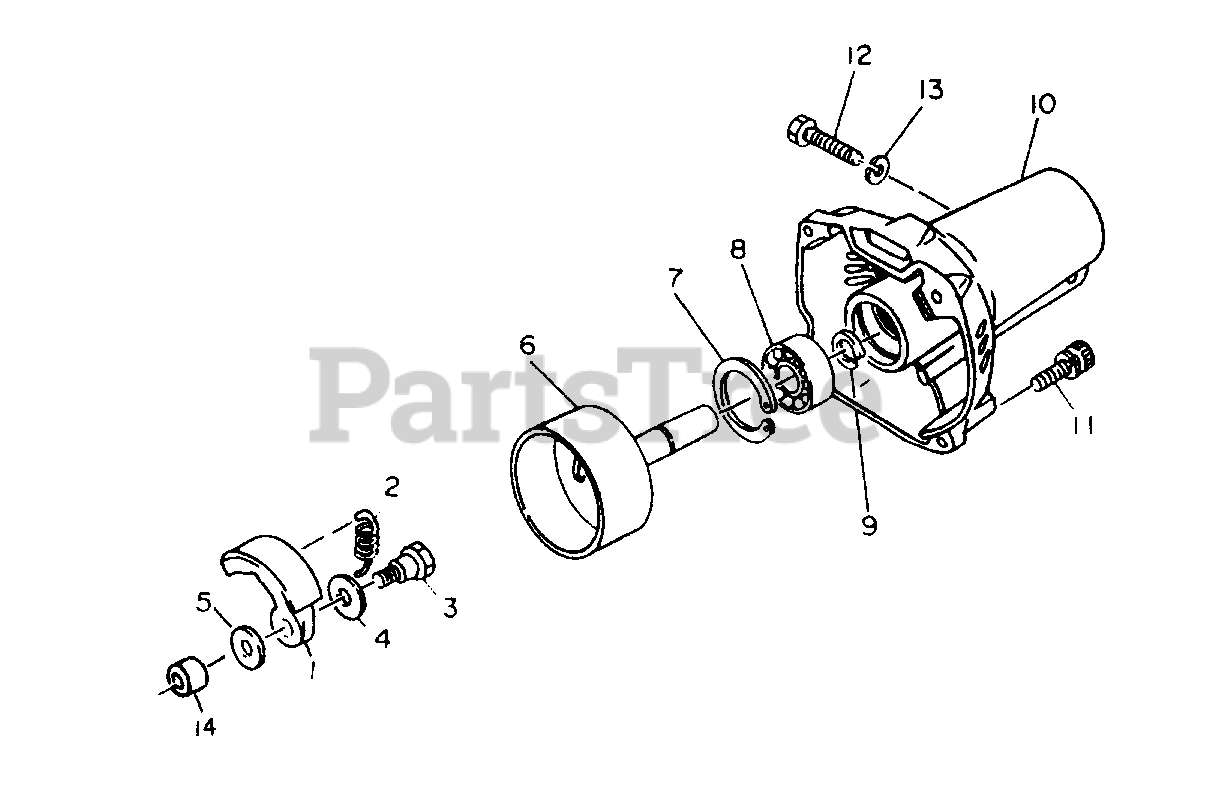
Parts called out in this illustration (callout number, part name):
6	Drum (Outside vendor part number)
7	Ring, Inner Retainer
8	Ball Bearing
9	Ring, Outer Retaining
10	Housing
11	Bolt, Socket Head
13	Washer, Spring
